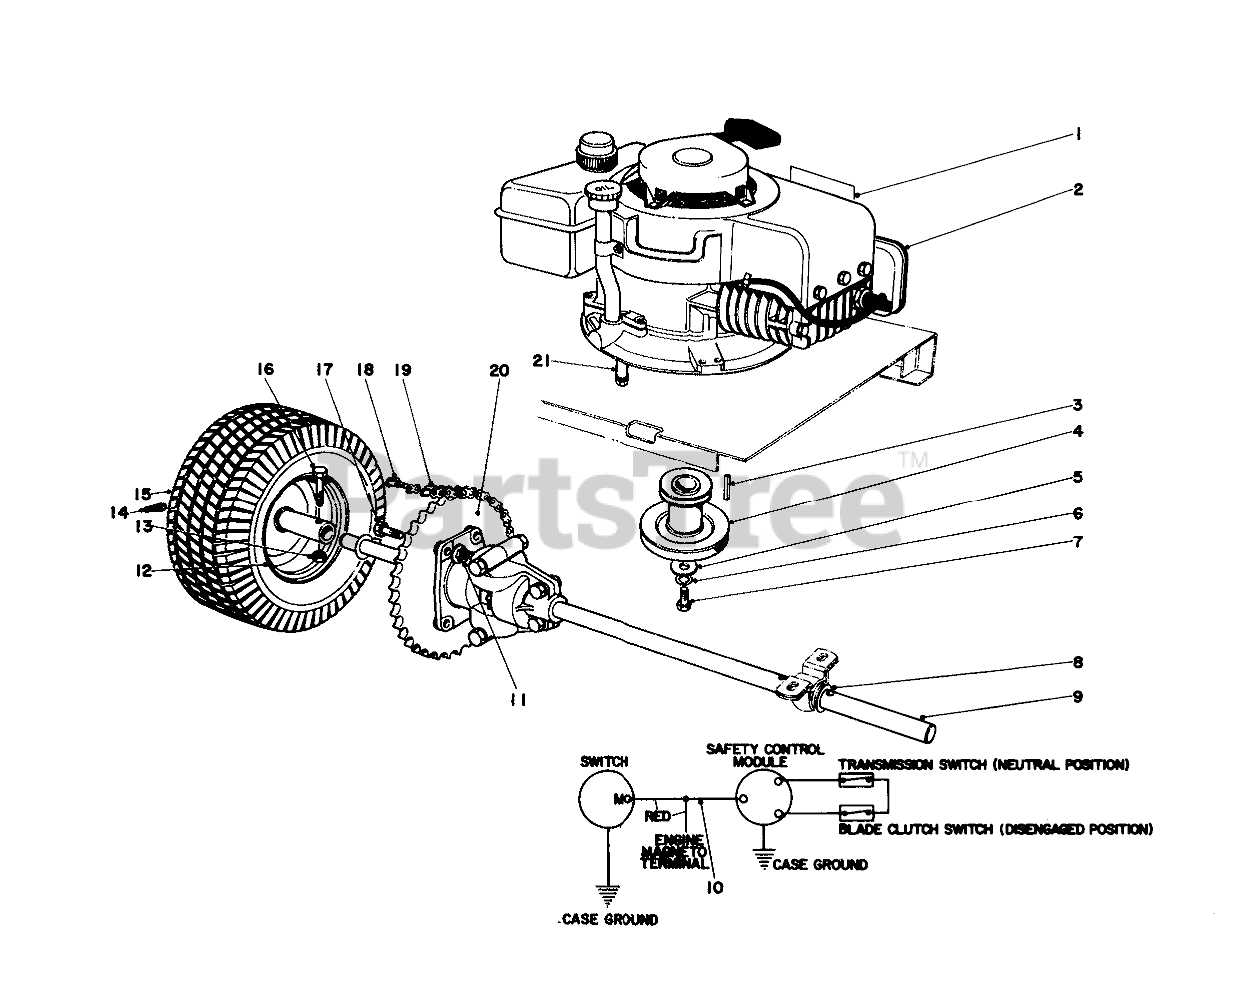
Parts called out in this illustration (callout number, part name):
1	Decal
2	Engine
4	ENGINE SHEAVE
5	Washer
6	WASHER-LOCK
7	SCREW-HH
8	WASHER
9	Differential
10	Wiring Harness
11	NUT-HF
13	NUT-LOCK, CONE
14	STEM-VALVE
15	Terra Tire
16	SCREW-HH
17	SCREW-HH
18	LINK-CONNECTING
19	Chain
20	Sprocket
21	Extension Oil Drain
